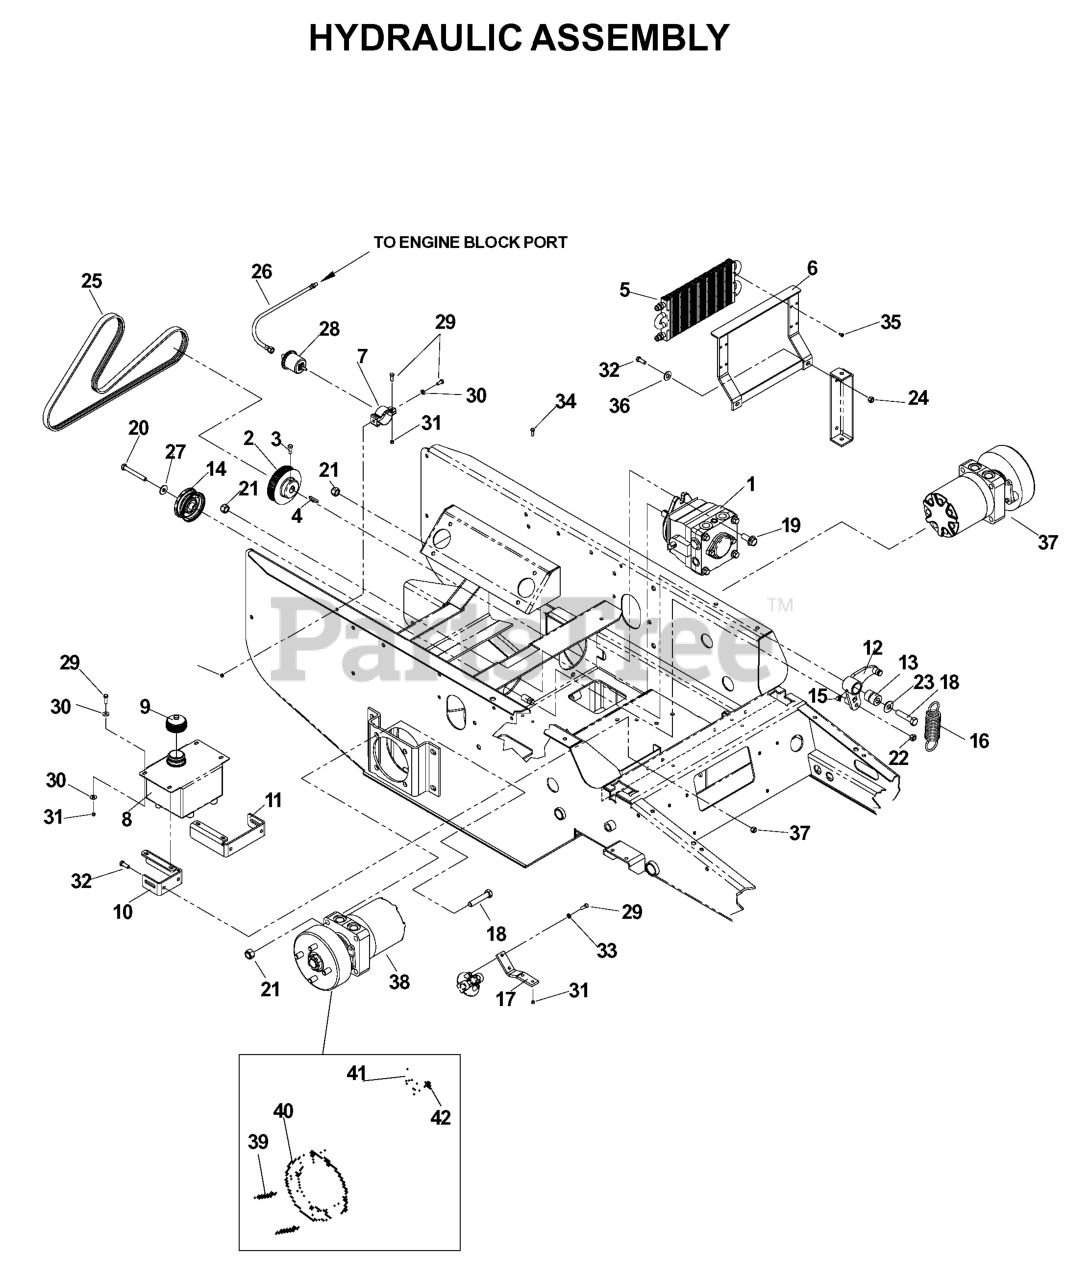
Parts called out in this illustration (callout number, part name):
1	HG_PUMP CCW RH
2	PUMP SHEAVE
3	SCREW, HEAD SET 5/16C X 3/4 SQ
4	KEY 5 MM SQ X 25 MM
6	COOLER WLDMT MT
7	CLAMP-OIL SENDER
8	TANK, OIL = PAINTED
9	HYDRAULIC CAP
10	TANK MOUNT RT
11	TANK MOUNT LT
12	ARM WELDMENT
14	IDLER PULLEY
17	FILTER MOUNT - PAINTED
18	HEX SCREW 1/2-13 X 2.5" GR 5
19	HCS 1/2C X 1 1/4 SERRATED HEAD
20	HCS 3/8C X 3
21	NUT 1/2-13 HEX NYLOC ZD
22	NUT 3/8-16 NYLOC
23	WASHER 1/2 FLAT
24	NUT 5/16 NYLOC
27	WASHER 3/8 SAE FLAT
28	SENDER,OIL PRESS
29	HCS 1/4C X 3/4 HCS
30	WASHER 1/4 FLAT
31	NUT.1/4-20.HEX.NYLOC.ZD
32	HCS 5/16C X 1
33	LOCKWASHER 1/4"
34	HCS 1/4 X 1
35	HSMS #10 X 5/8
36	WASHER 5/16 FLAT
37	WHEEL MTR ASM
38	WHEEL MTR ASM, RT
39	RETURN SPRING
